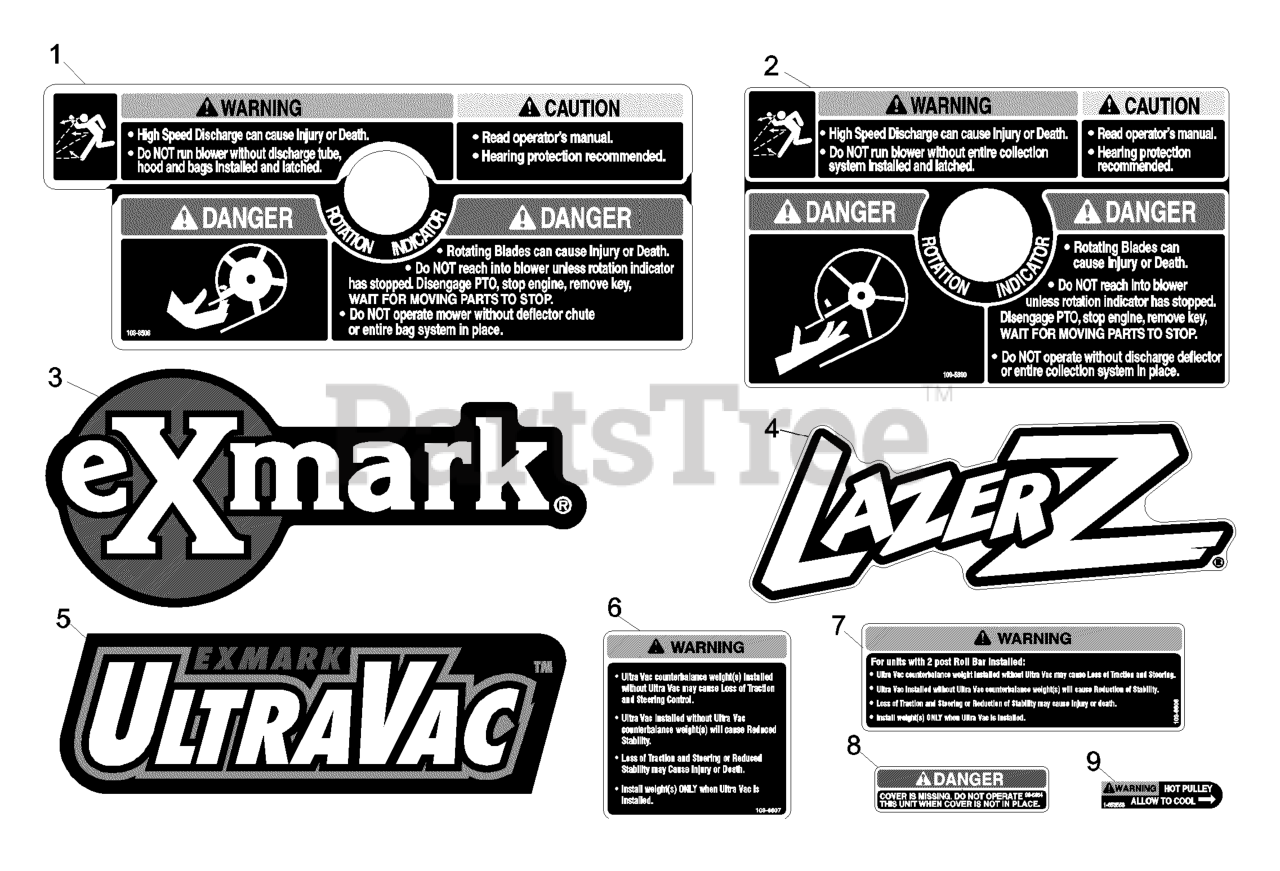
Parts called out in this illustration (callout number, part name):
1	DECAL-WARNING
2	DECAL-WARNING, BLOWER
3	DECAL, EXMARK LOGO
4	DECAL,LAZER MODEL
5	DECAL, ULTRAVAC
6	DECAL,WEIGHT
7	DECAL,WEIGHT
8	DECAL-COVER, MISSING
9	DECAL-WARNING
